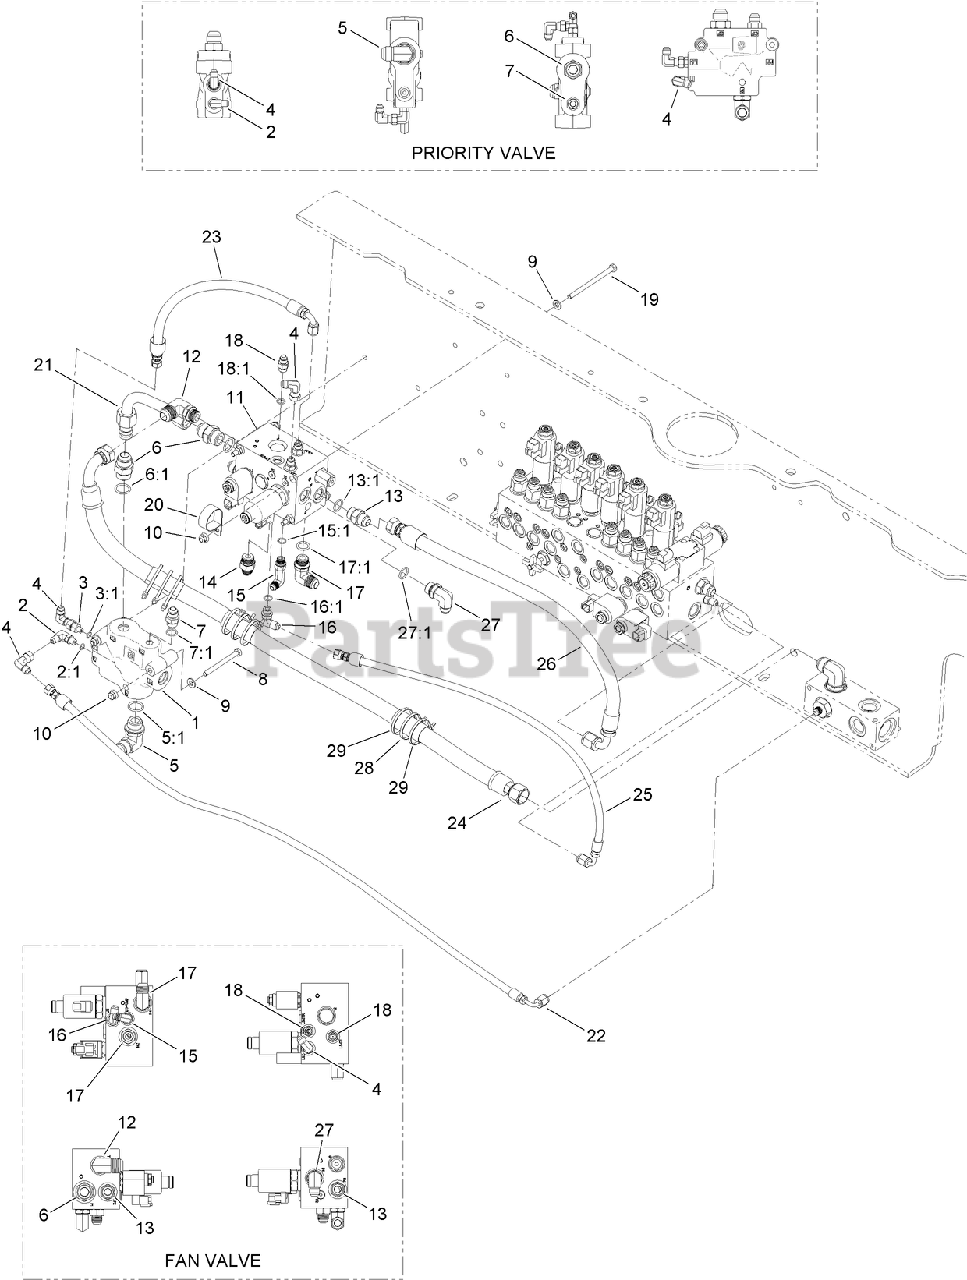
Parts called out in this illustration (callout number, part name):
1	VALVE-FLOW DIVIDER, PRIORITY
2	ELBOW-90, ADJ
2:1	O-RING
3	ADAPTER-STRAIGHT
3:1	O-RING
4	ELBOW-SWIVEL, 90 DEG
5	FITTING-ELBOW, 90 DEG
5:1	O-RING
6	FITTING-STRAIGHT
6:1	O-RING
7	FITTING-STRAIGHT
7:1	O-RING
8	SCREW-HH
9	WASHER-PLAIN
10	NUT-LOCK, HHF
11	VALVE-FAN DRIVE
12	FITTING-ELBOW, 90 DEG
13	FITTING-STRAIGHT
13:1	O-RING
14	FITTING-STRAIGHT
15	FITTING-ADAPTOR, 90 DEG
15:1	O-RING
16	FITTING-ELBOW, 90 DEG
16:1	O-RING
17	FITTING-ELBOW, 90 DEG
17:1	O-RING
18	FITTING-STRAIGHT
18:1	O-RING
19	SCREW-HH
20	CLAMP-R
22	HYD HOSE ASM
23	HYD HOSE ASM
24	HYD RETURN HOSE ASM
25	HYD HOSE ASM
26	HYD HOSE ASM
27	FITTING-90 DEG
27:1	O-RING
28	PROTECTOR-HOSE
29	TIE-CABLE
